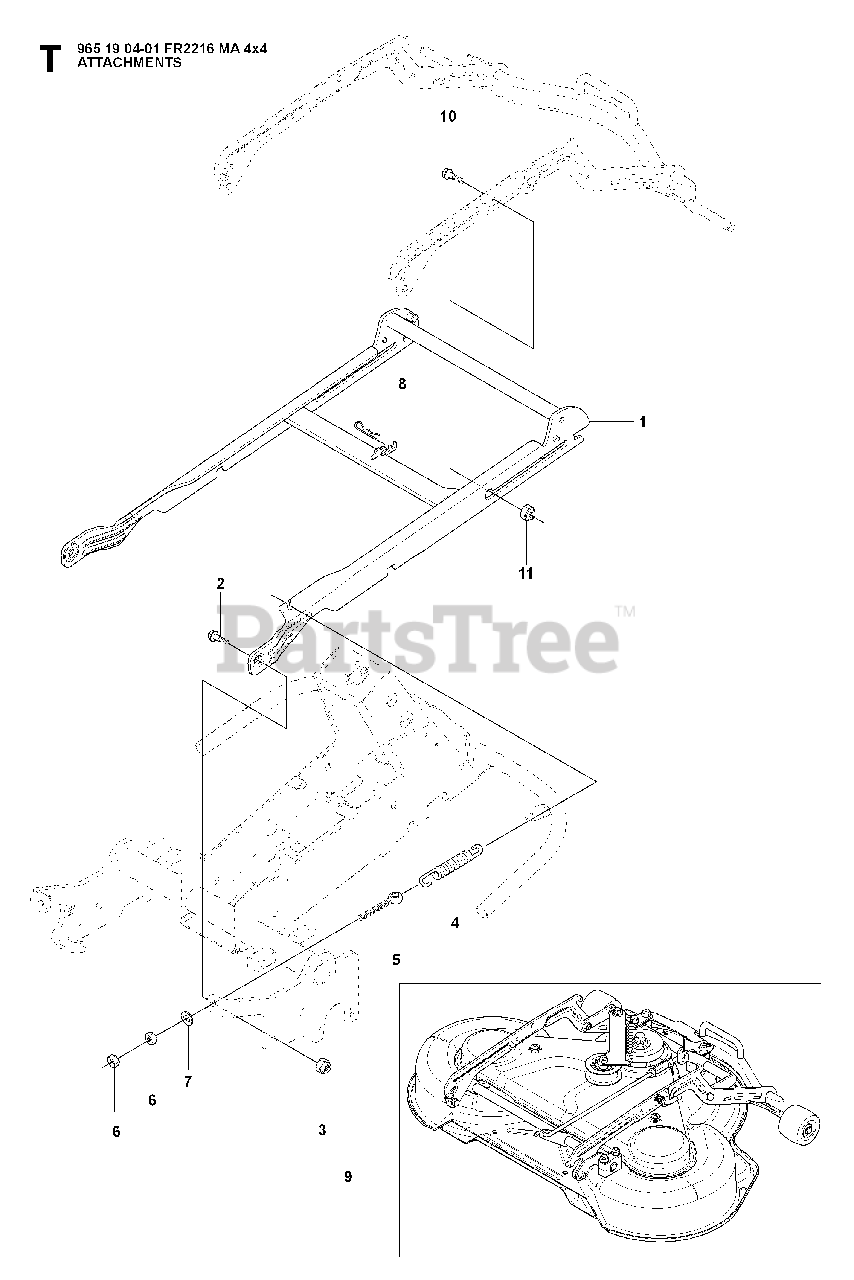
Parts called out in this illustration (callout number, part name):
7	WASHER
10	COLLAR SCREW
11	LOCKNUT M8
